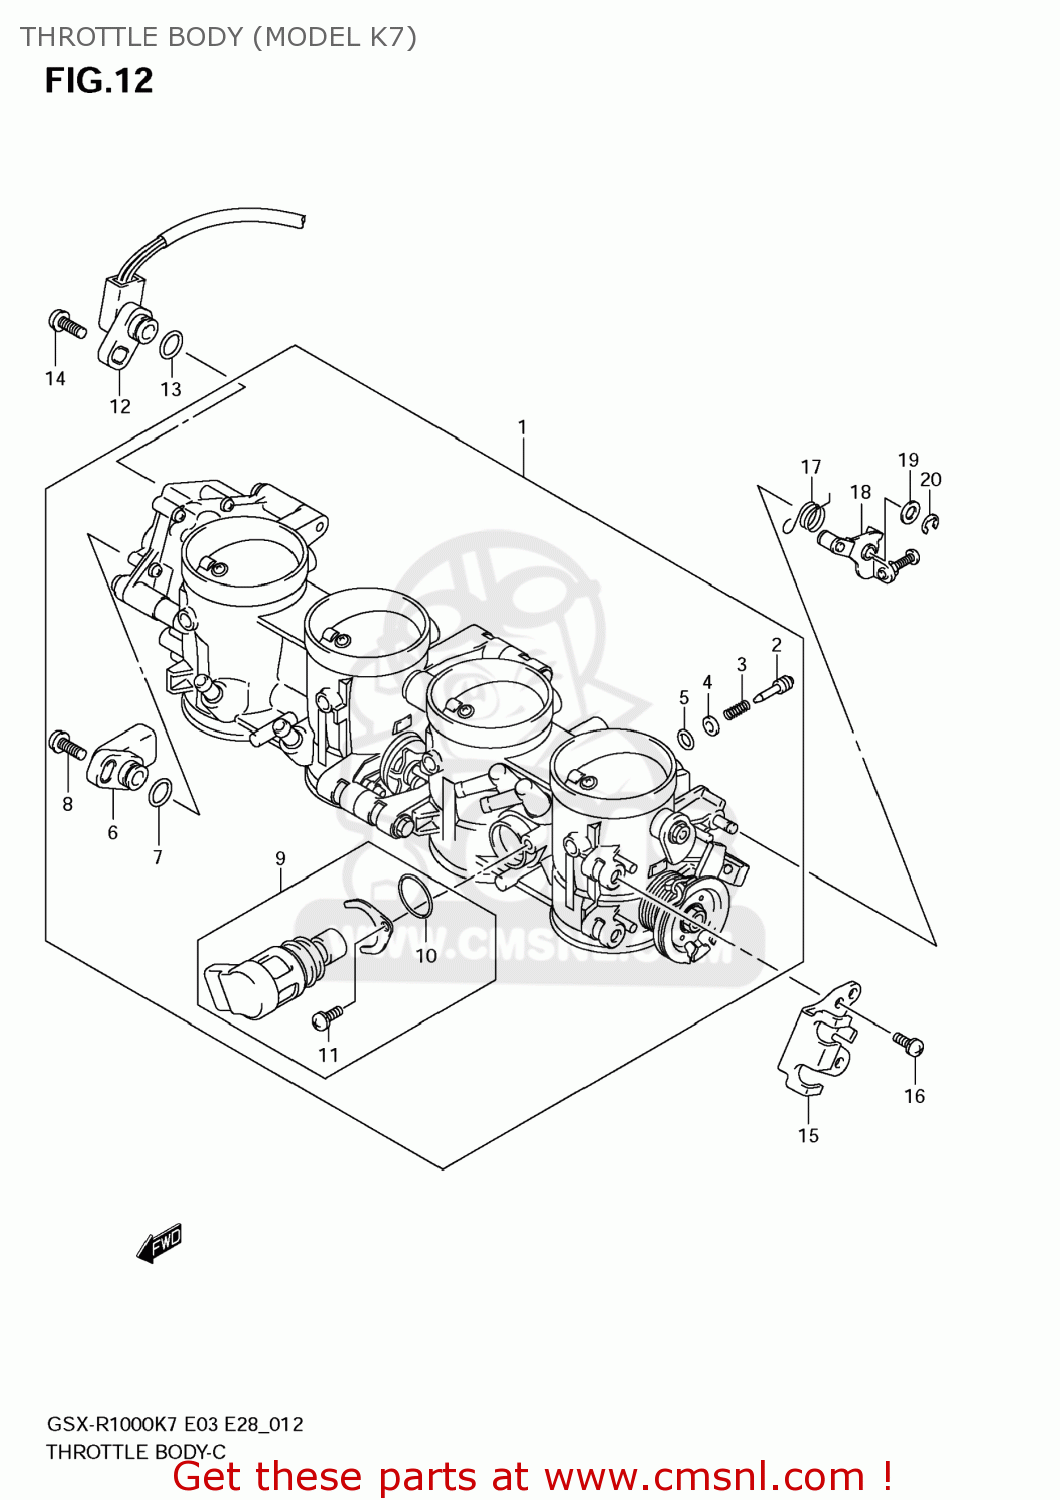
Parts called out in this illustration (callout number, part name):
1	THROTTLE BODY
2	SCREW,AIR ADJUST
3	SPRING
4	WASHER
5	O RING
6	SENSOR ASSY,THROTTLE MAIN
7	O RING
8	SCREW
9	VALVE SET,ISC
10	O RING
11	SCREW
12	SENSOR ASSY,TH
13	O RING
14	SCREW
15	PLATE,STAY
16	SCREW
17	SPRING
18	LEVER ASSY,LINK
19	WASHER
20	E CLIP
